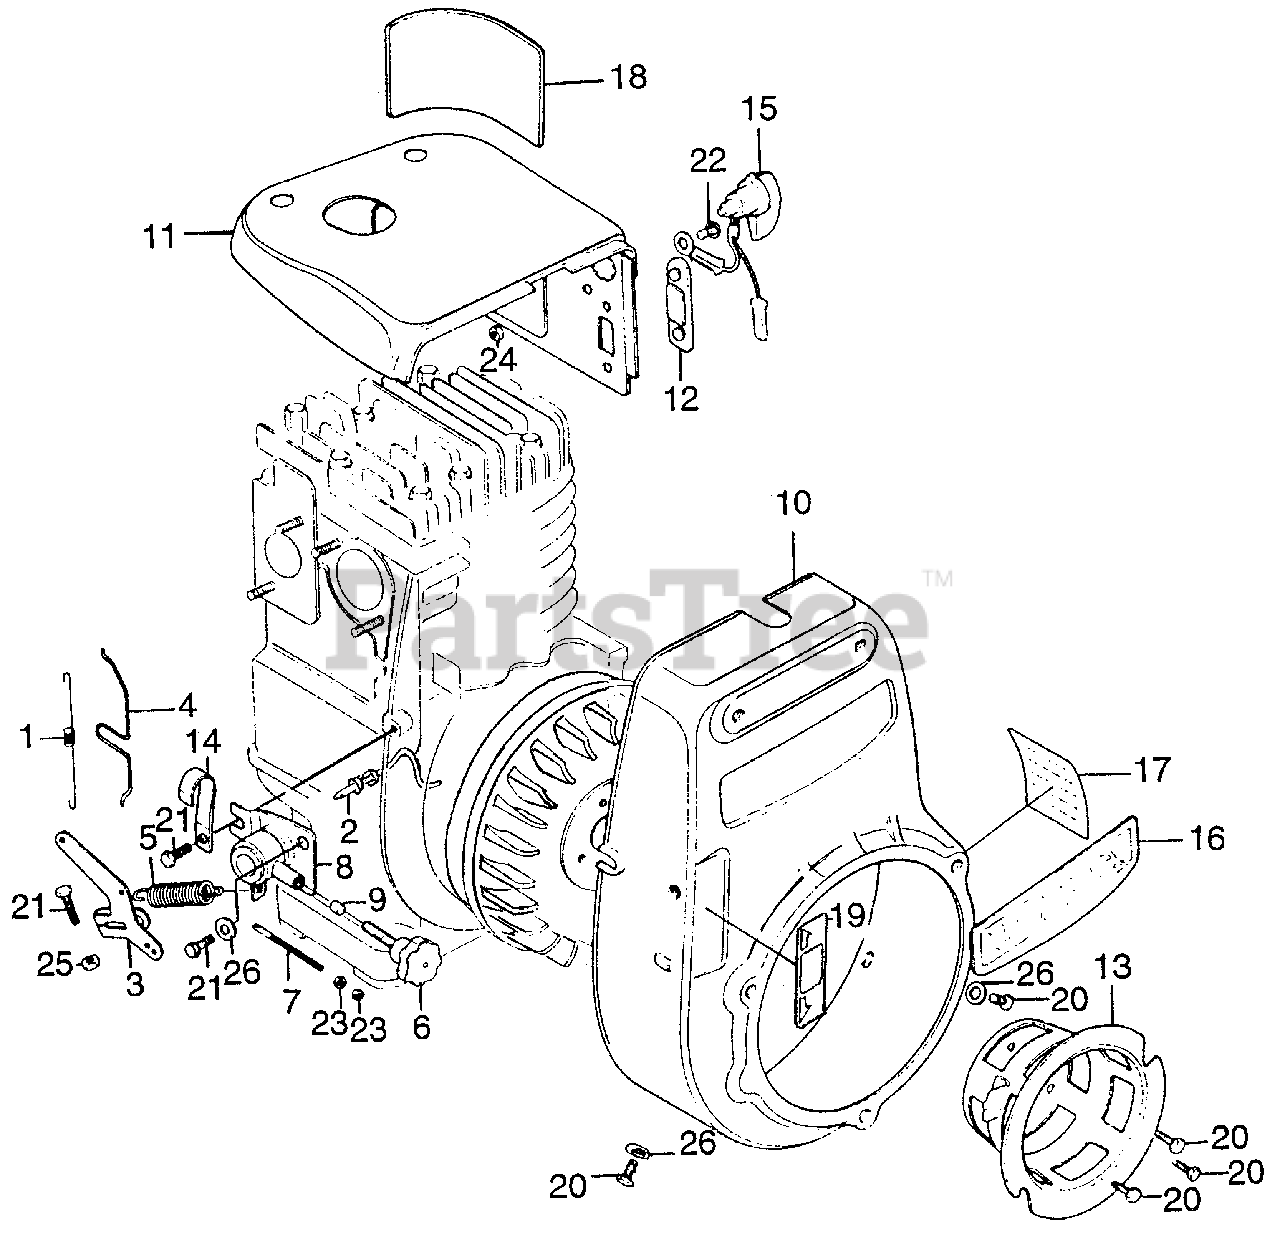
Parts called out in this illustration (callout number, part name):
1	SPRING, THROTTLE RETURN (NOT AVAILABLE)
2	SHAFT, GOVERNOR ARM
3	ARM, GOVERNOR
4	ROD, GOVERNOR
5	SPRING, GOVERNOR (NOT AVAILABLE)
6	SCREW, GOVERNOR ADJUST (NOT AVAILABLE)
7	BOLT, SPRING ADJUSTING (NOT AVAILABLE)
8	LEVER, CONTROL (NOT AVAILABLE)
9	BUSHING, CONTROL
10	COVER, FAN *R8* (BRIGHT RED) (NOT AVAILABLE)
11	COVER, SIDE *R8* (BRIGHT RED)
12	DEFENDER, SIDE COVER
13	PULLEY, STARTER (NOT AVAILABLE)
13	PULLEY, STARTER
14	CLAMP, WIRE
15	SWITCH ASSY., ENGINE STOP (NOT AVAILABLE)
16	EMBLEM (NOT AVAILABLE)
17	MARK, DIPSTICK OIL (NOT AVAILABLE)
18	PLATE, DESCRIPTION
20	BOLT, HEX. (6X12)
21	BOLT, HEX. (6X16)
22	SCREW, PAN (5X10)
23	NUT, HEX. (4MM)
24	NUT, HEX. (5MM)
25	NUT, HEX. (6MM)
26	WASHER, PLAIN (6MM)
